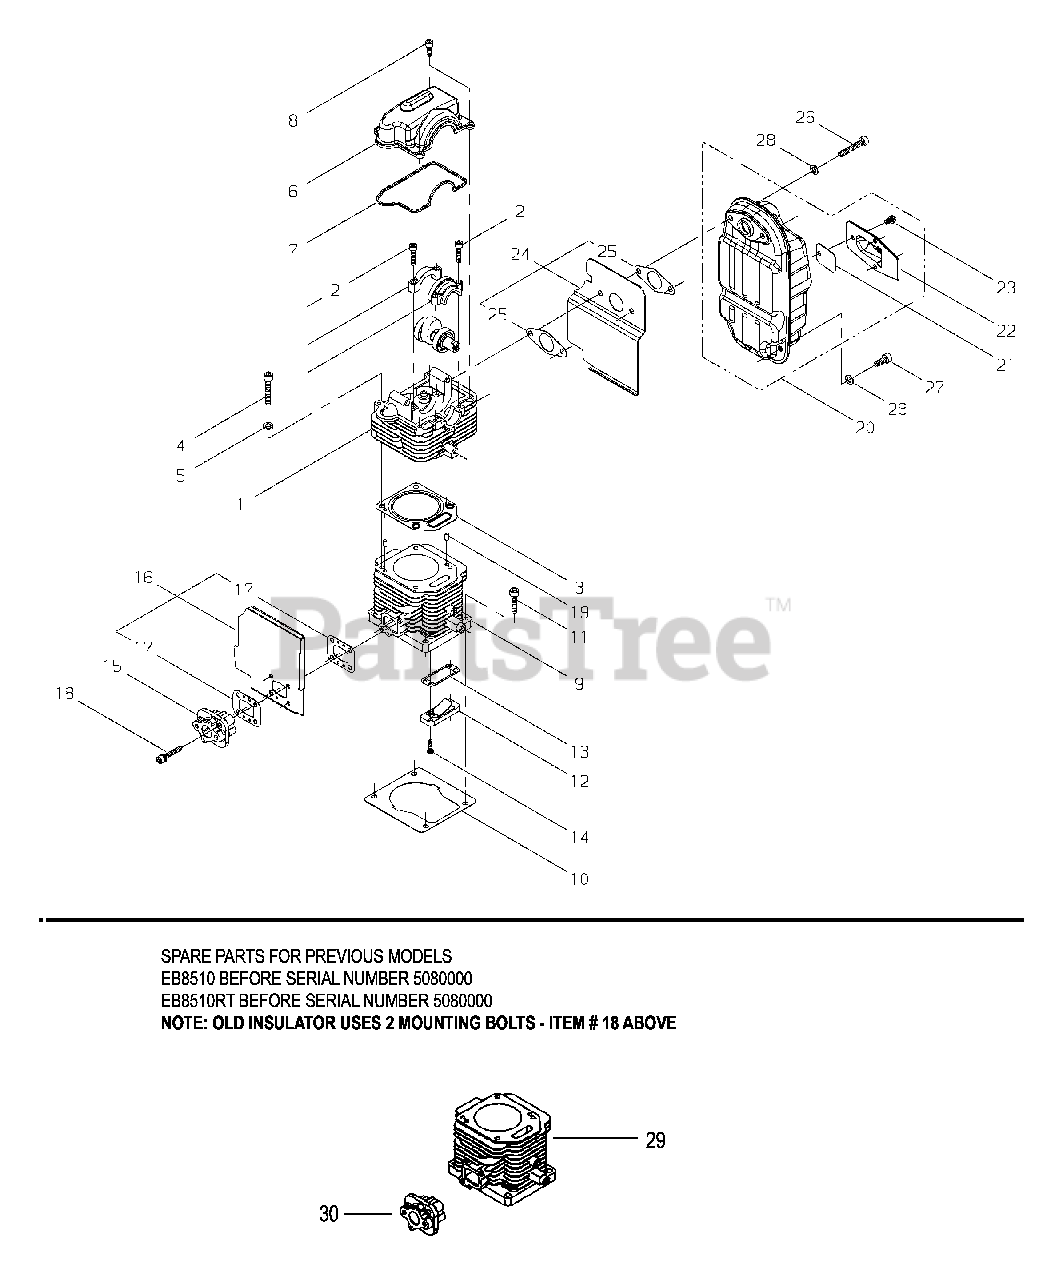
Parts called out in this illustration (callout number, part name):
1	CYLINDER HEAD ASSY
2	SCREW - 5X22
3	GASKET
4	SCREW - 6X35
6	COVER, ROCKER ARM
7	GASKET
8	SCREW - 5X14
9	CYLINDER
10	GASKET
11	SCREW - 6X25
12	REED VALVE ASSY
13	GASKET
14	SCREW - 4X14
15	INSULATOR
16	INTAKE SHIELD KIT
17	GASKET, INTAKE
18	SCREW - 5X30
19	PIN - LOCATING
20	MUFFLER ASSY
21	SCREEN, SPARK ARRESTOR
22	TAIL PLATE
23	SCREW - 5X8
24	GASKET
25	GASKET
26	SCREW - 6X35
27	SCREW - 6X16
28	WASHER - 6
29	CYLINDER
30	INSULATOR
